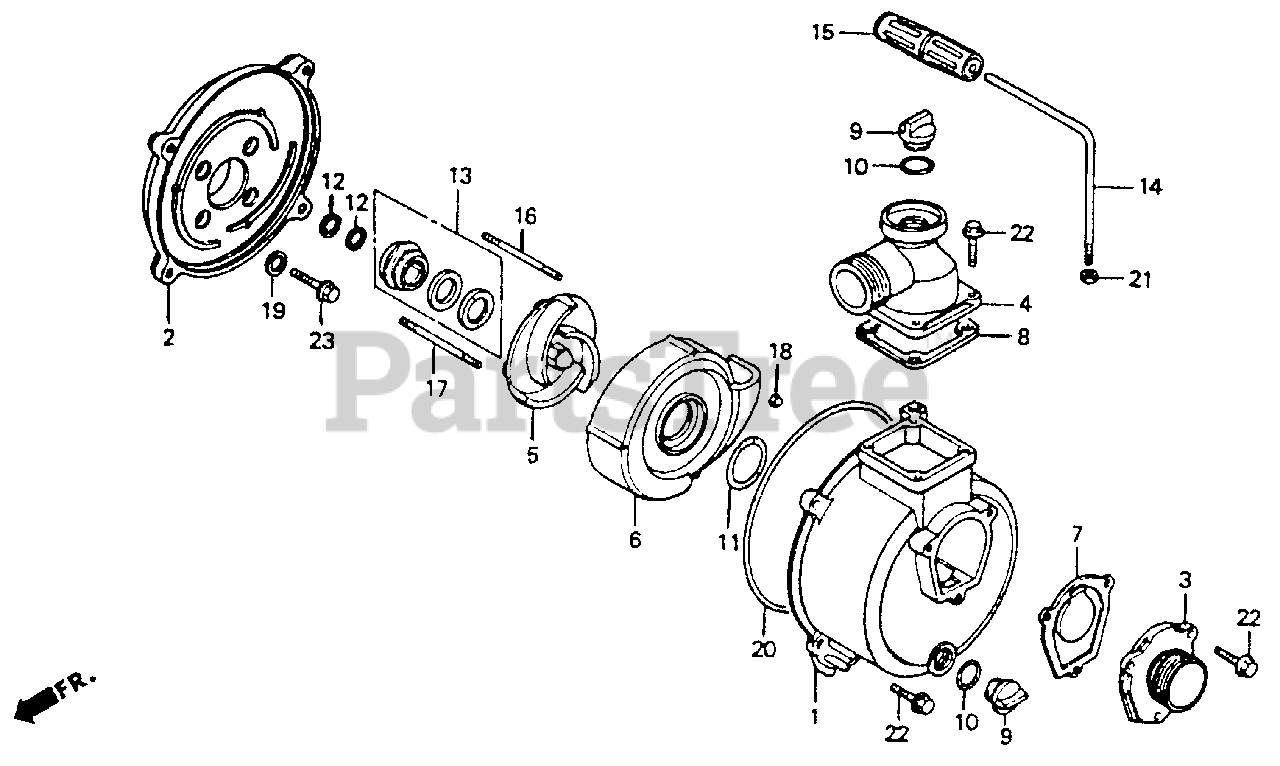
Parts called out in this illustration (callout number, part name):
1	CASING
2	COVER, CASING
3	PIPE, INLET
4	PIPE, OUTLET
6	CASE, VOLUTE
7	VALVE, IN.
8	GASKET, OUTLET
9	CAP, FILLER
10	RING, SEAL (B)
11	O-RING (49X5.7) (NOK)
12	SHIM, ADJUSTER
13	SEAL ASSY., MECHANICAL WATER
15	GRIP, HANDLE
16	BOLT, STUD (6X50)
17	BOLT, STUD (6X50)
18	NUT, CAP (6MM)
19	WASHER, SEALING (8MM)
20	O-RING (217.5X3.5) (ARAI)
21	NUT, HEX. (12MM)
21	NUT, HEX. (14MM)
22	BOLT, FLANGE (8X25)
23	BOLT, FLANGE (8X28)
